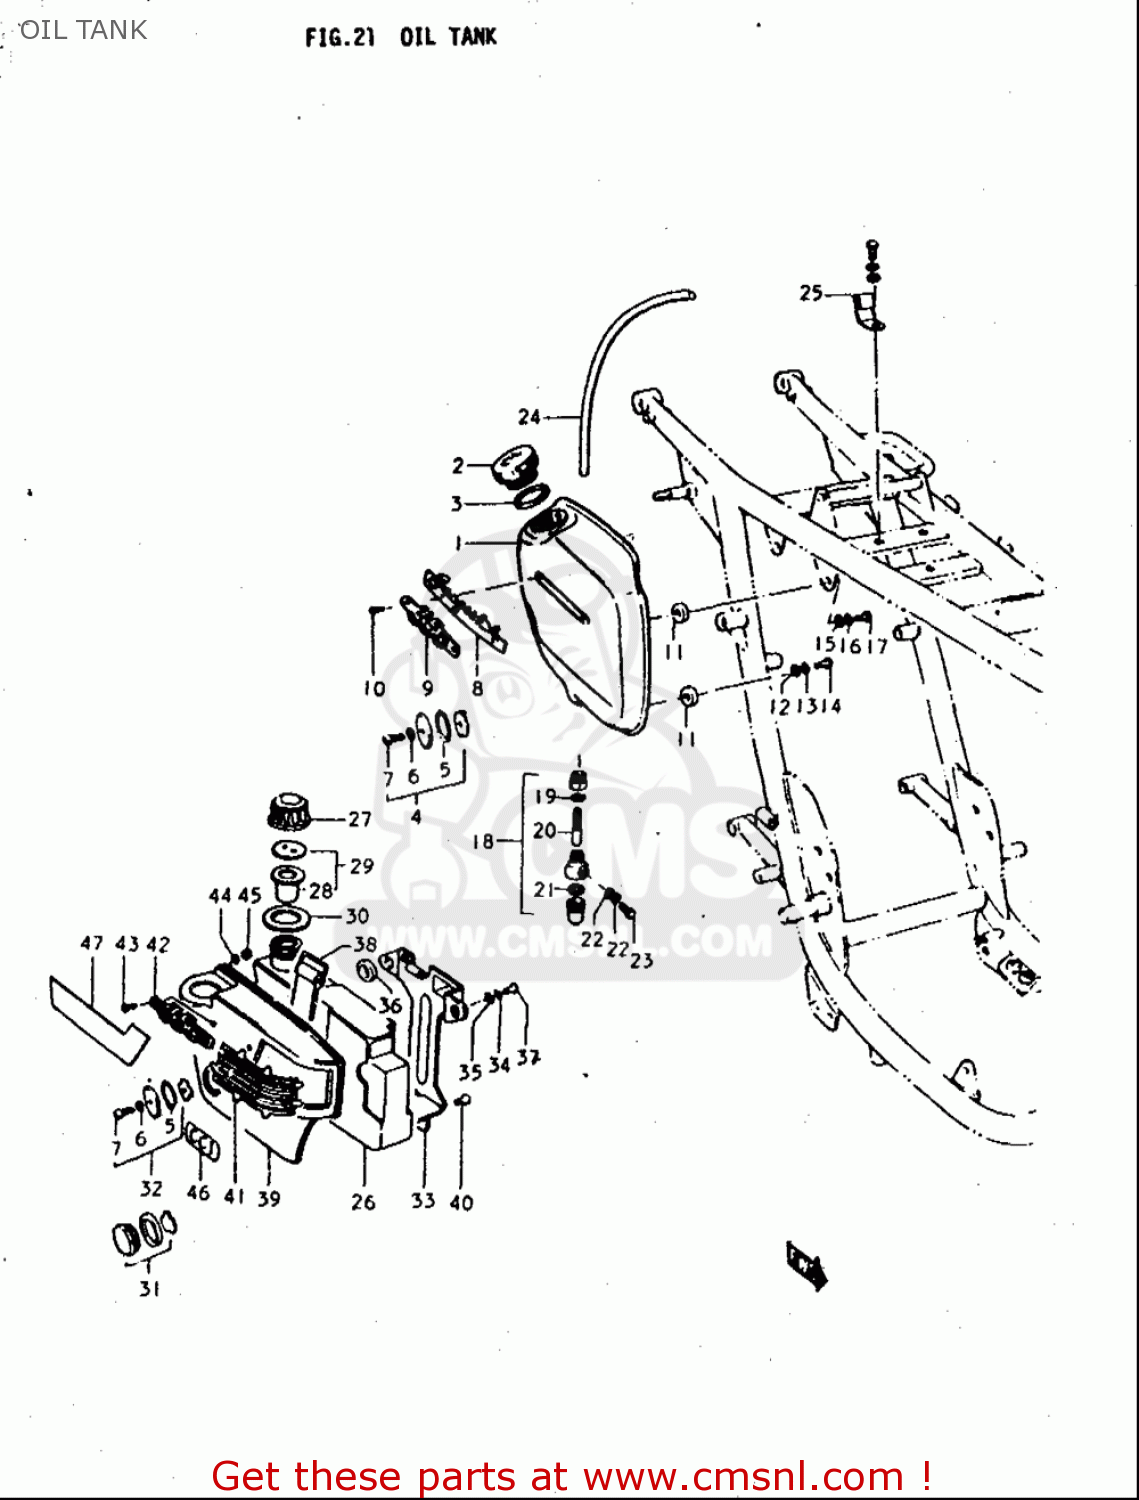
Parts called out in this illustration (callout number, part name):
2	CAP,OIL TANK
3	GASKET,OIL TANK FILLER CAP (NAS)
4	LENS SET,OIL INSPECTION
5	O RING(D:3,ID:23)
6	GASKET(5X9.5X1) (NAS)
7	SCREW
10	SCREW
11	WASHER
12	WASHER(6.5X18X1.6)
13	WASHER,LOCK
15	WASHER
16	WASHER,LOCK
17	BOLT(6X14)
19	GASKET,OIL OUTLET JOINT (NAS)
20	UNIT,OIL FILTER
22	GASKET(6.2X11X1).2 (NAS)
23	UNION BOLT
27	CAP,OIL TANK
29	GASKET,OIL TANK CAP (NAS)
30	RUBBER,FUEL TANK INLET
31	LENS SET,OIL LEVEL
34	WASHER,LOCK
35	WASHER
36	WASHER(6.5X18X1.6)
37	SCREW(6X12)
38	BAND
40	SCREW
44	WASHER,LOCK
45	NUT
46	EMBLEM,CCIS
